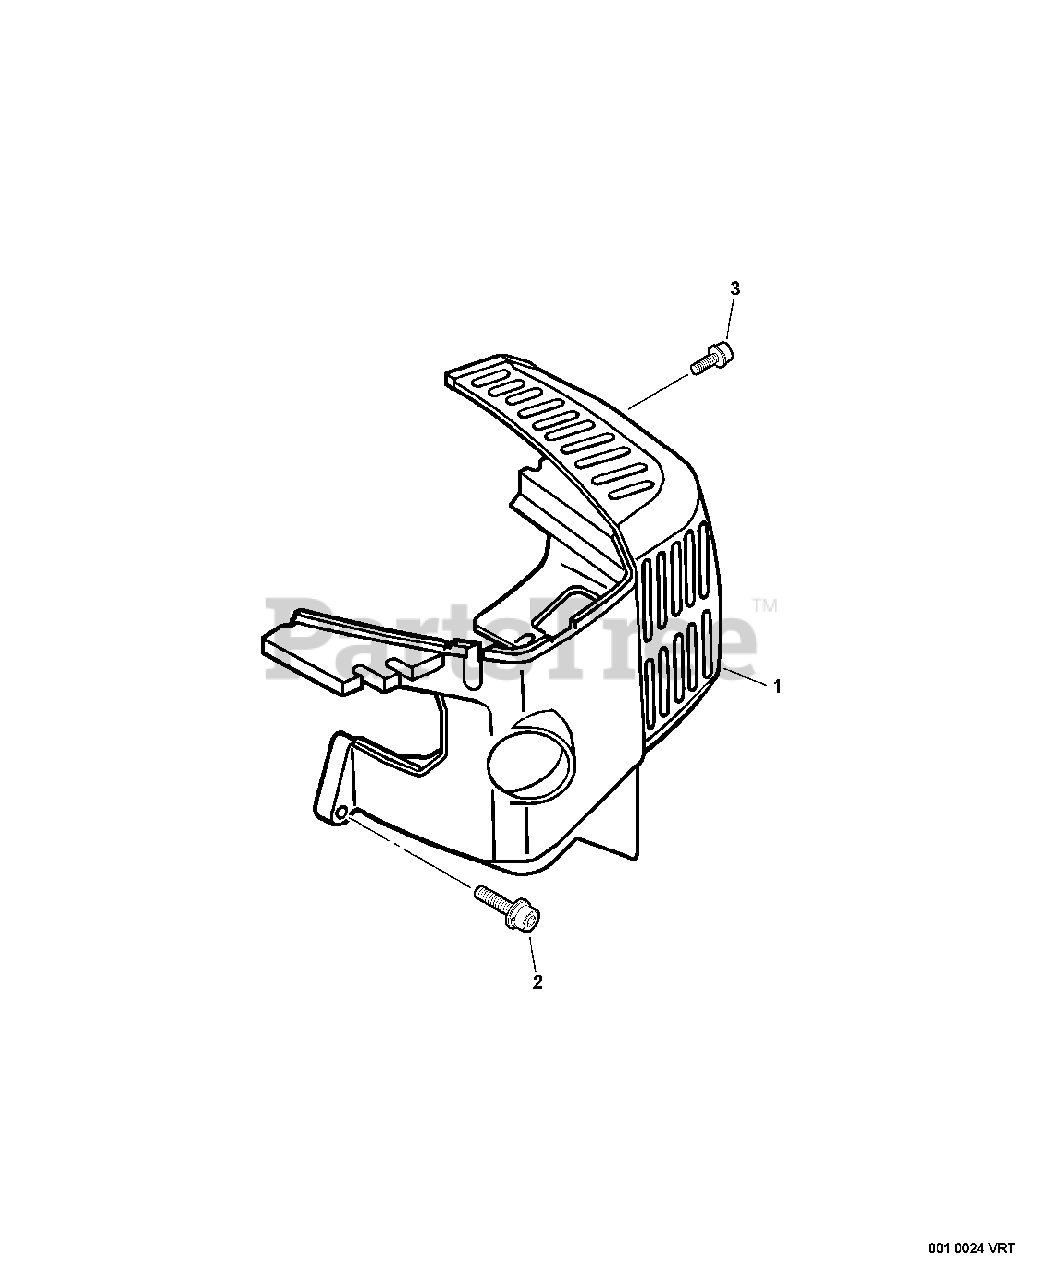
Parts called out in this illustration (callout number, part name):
1	COVER, ENGINE
2	SCREW - 4X22
3	SCREW - 4X8
